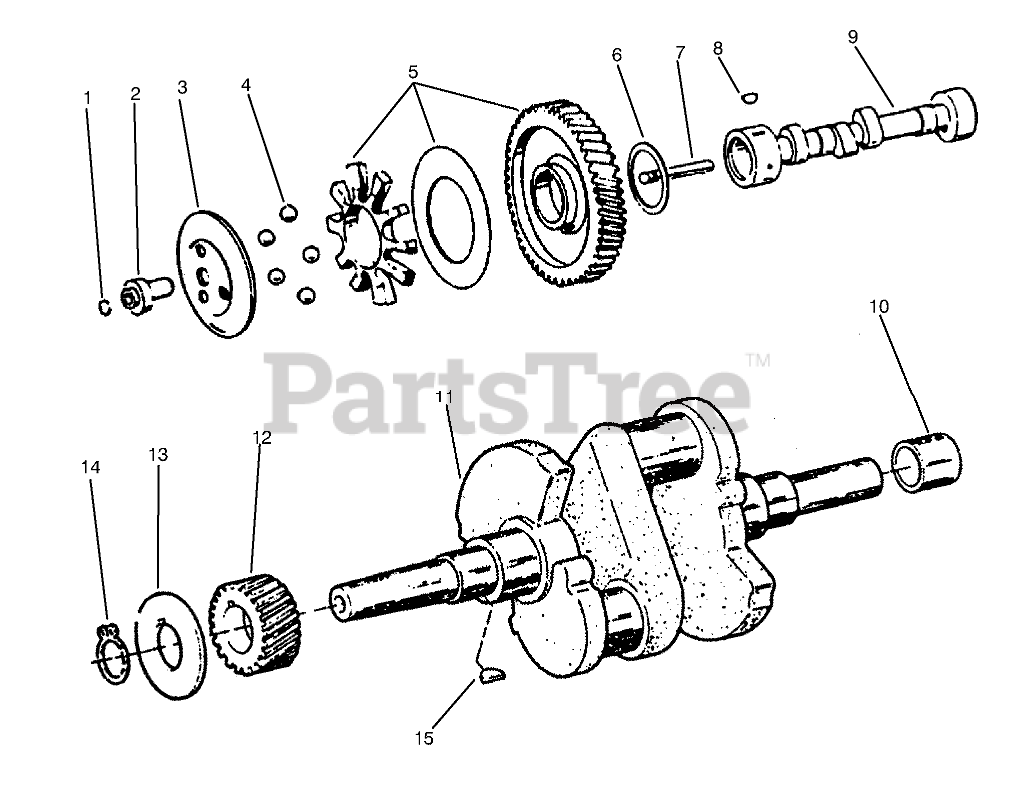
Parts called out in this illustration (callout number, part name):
2	HUB-GOVERNOR CUP
3	CUP-GOVERNOR
4	BEARING
5	GEAR ASM
6	WASHER-THRUST
7	PIN-CENTER
9	CAMSHAFT (16&18HP)
10	BEARING SLEEVE
11	CRANK-SHAFT
13	WASHER
